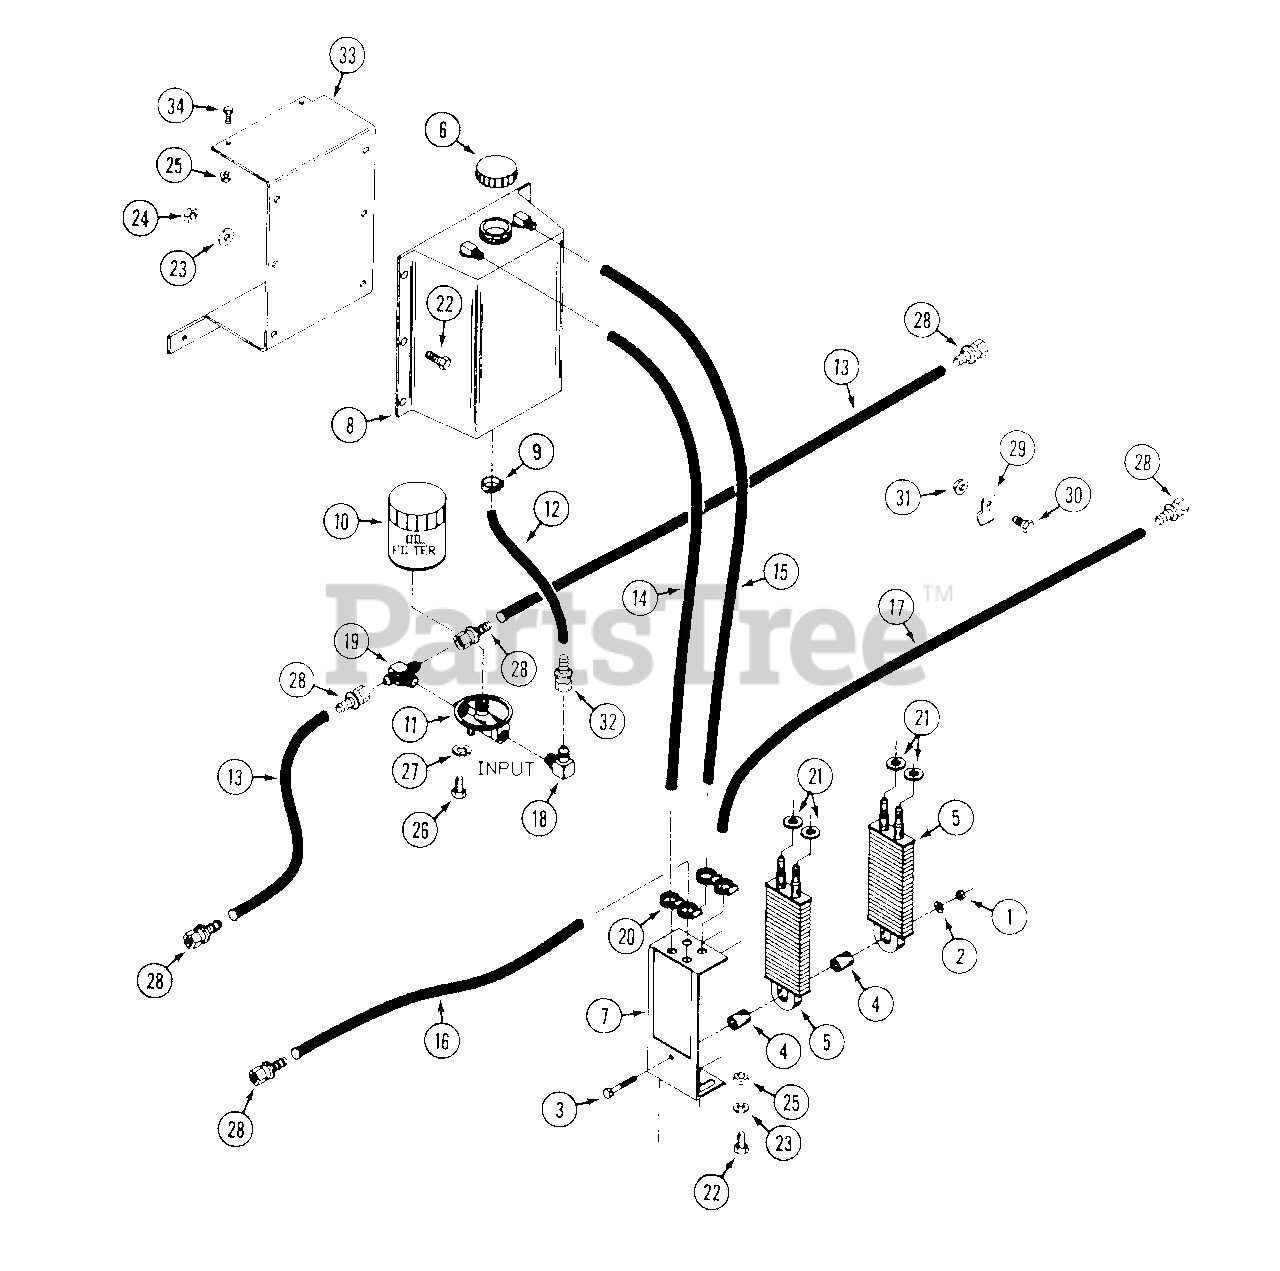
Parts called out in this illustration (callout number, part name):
1	NUT - lock 5/16"
2	WASHER - 5/16"
3	BOLT - 5/16" - 18 x 2-3/4"
4	BUSHING - rubber
6	CAP - oil tank
7	MOUNT - oil cooler
8	TANK - oil
9	CLAMP - hose 5/8"
10	FILTER - oil
11	HEAD - oil filter
12	HOSE - 5/8" x 11"
13	HOSE - hydraulic 3/8" x 13"
14	HOSE - hydraulic 3/8" x 25"
15	HOSE - hydraulic 3/8" x 27"
16	HOSE - hydraulic 3/8" x 38"
17	HOSE - hydraulic 3/8" x 24"
18	FITTING - male 90° adapter
19	FITTING - male tee adapter
20	CLAMP - hose 3/8"
21	GROMMET - 1/2" ID x 1" OD
22	BOLT - 1/4" - 20 x 3/4"
23	WASHER - 1/4"
24	NUT - 1/4" - 20 lock
25	NUT - 1/4" - 20 flange lock
26	BOLT - 1/4" - 20 x 3/4" self-tap
27	LOCKWASHER - 1/4"
28	FITTING - 3/8" hose barb x 3/8" FM JIG
29	CLIP - "J"
30	BOLT - 5/16" x 18 x 3/4"
31	NUT - 5/16" - 18 flange lock
32	FITTING - 5/8" hose barb x 1/2" FM JIC
33	MOUNT - oil tank
34	BOLT - 1/4" - 20 x 1/2"
